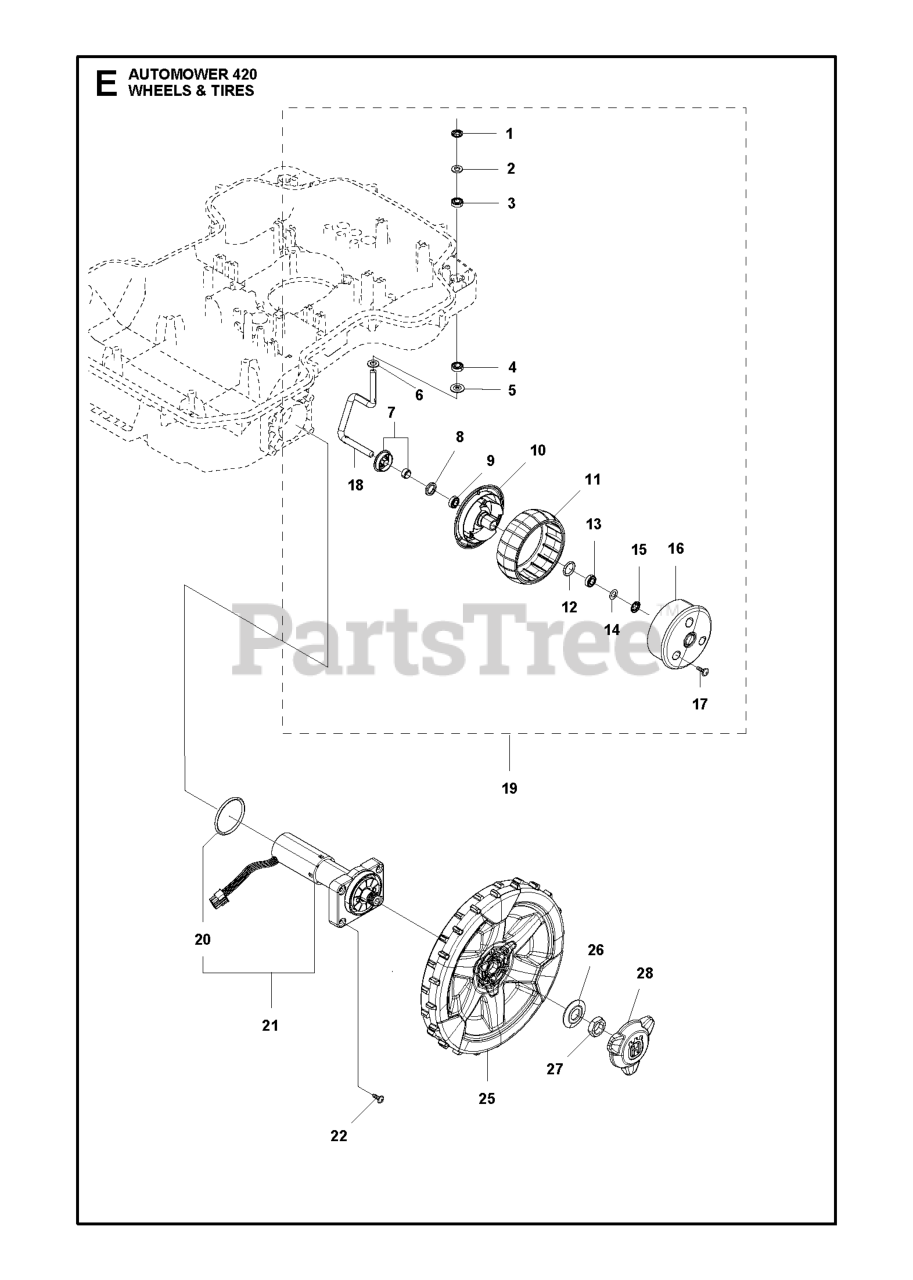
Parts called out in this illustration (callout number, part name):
1	LOCKWASHER PUSH-ON TYPE P 8 BV
2	WASHER DIN 988 13X8X0.5
3	BALL BEARING SINGLE ROW S688
4	BALL BEARING SINGLE ROW S688
5	WASHER FRONT WHEEL CENTER HOLE
6	WASHER DIN 988 13X8X0.5
7	SHIELD KIT
8	SEALING 12X18X3
9	BALL BEARING SINGLE ROW S688
10	WHEEL FRONT WHEEL INSIDE
11	WHEEL RUBBER TYRE
12	O-RING 2,62X15,54
13	BALL BEARING SINGLE ROW S688
14	WASHER DIN 988 13X8X0.5
15	LOCKWASHER PUSH-ON TYPE P 8 BV
16	WHEEL FRONT WHEEL OUTSIDE
17	SCREW 14MM
18	SPINDLE SPINDLE FRONT WHEEL RI
19	WHEEL KIT FRONT
20	O-RING LIGHT GREY
22	SCREW ITXPANT
23	SCREW 14MM
25	WHEEL ASSY D249 HVA LIGHT GREY
26	WASHER WASHER REAR WHEEL 16X40
27	HEXAGON THIN NUT
28	HUB CAP REAR WHEEL NO CENTER P
